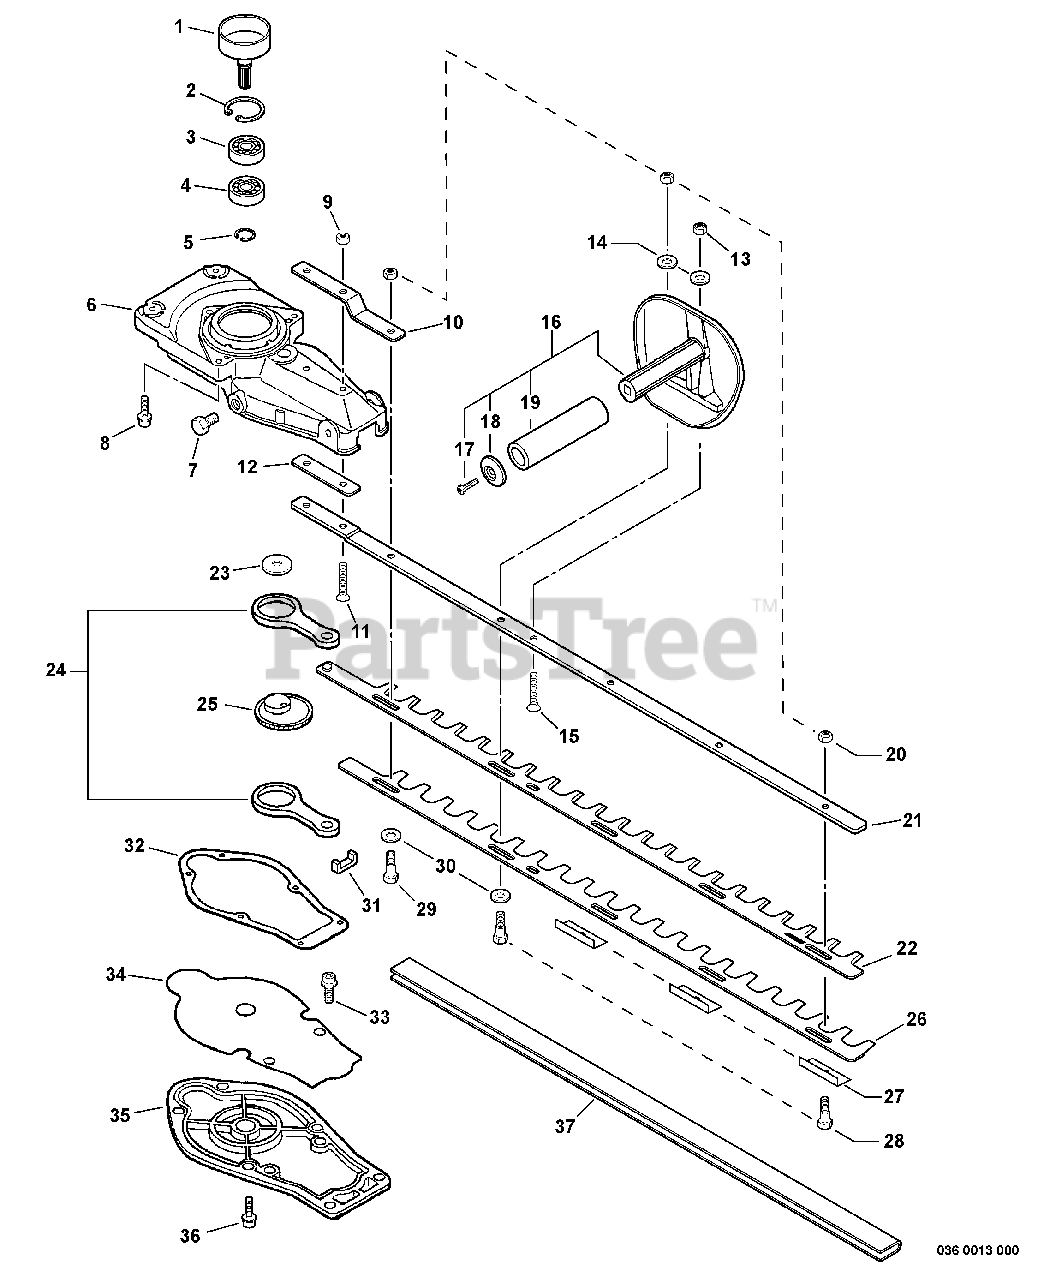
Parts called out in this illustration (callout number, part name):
1	DRUM, CLUTCH
2	RING, RETAINING - 35
3	BEARING, BALL - 6202
4	BEARING, BALL - 6202
5	RING, RETAINING - 14
6	CASE, GEAR - UPPER
7	BOLT - 8X8
8	SCREW - 5X25
9	LOCKNUT - 6
10	PLATE, ANGLE
11	SCREW - 6X25
13	LOCKNUT - 6
15	SCREW - 6X30
16	HANDLE ASSY - FRONT
17	SCREW - 5X14
19	GRIP, HANDLE
20	LOCKNUT - 6
21	SUPPORT, BLADE
22	BLADE - UPPER
24	ROD, CONNECTING
25	GEAR - DRIVE
26	BLADE - LOWER
27	INSULATOR
28	BOLT - 6X22
29	BOLT - 6X35
30	WASHER - 6
31	SEAL, FELT
32	GASKET, GEAR CASE
33	SCREW - 5X12
34	LID, GEAR CASE
35	LID, GEAR CASE - LOWER
36	SCREW - 4X12
37	COVER, BLADE
